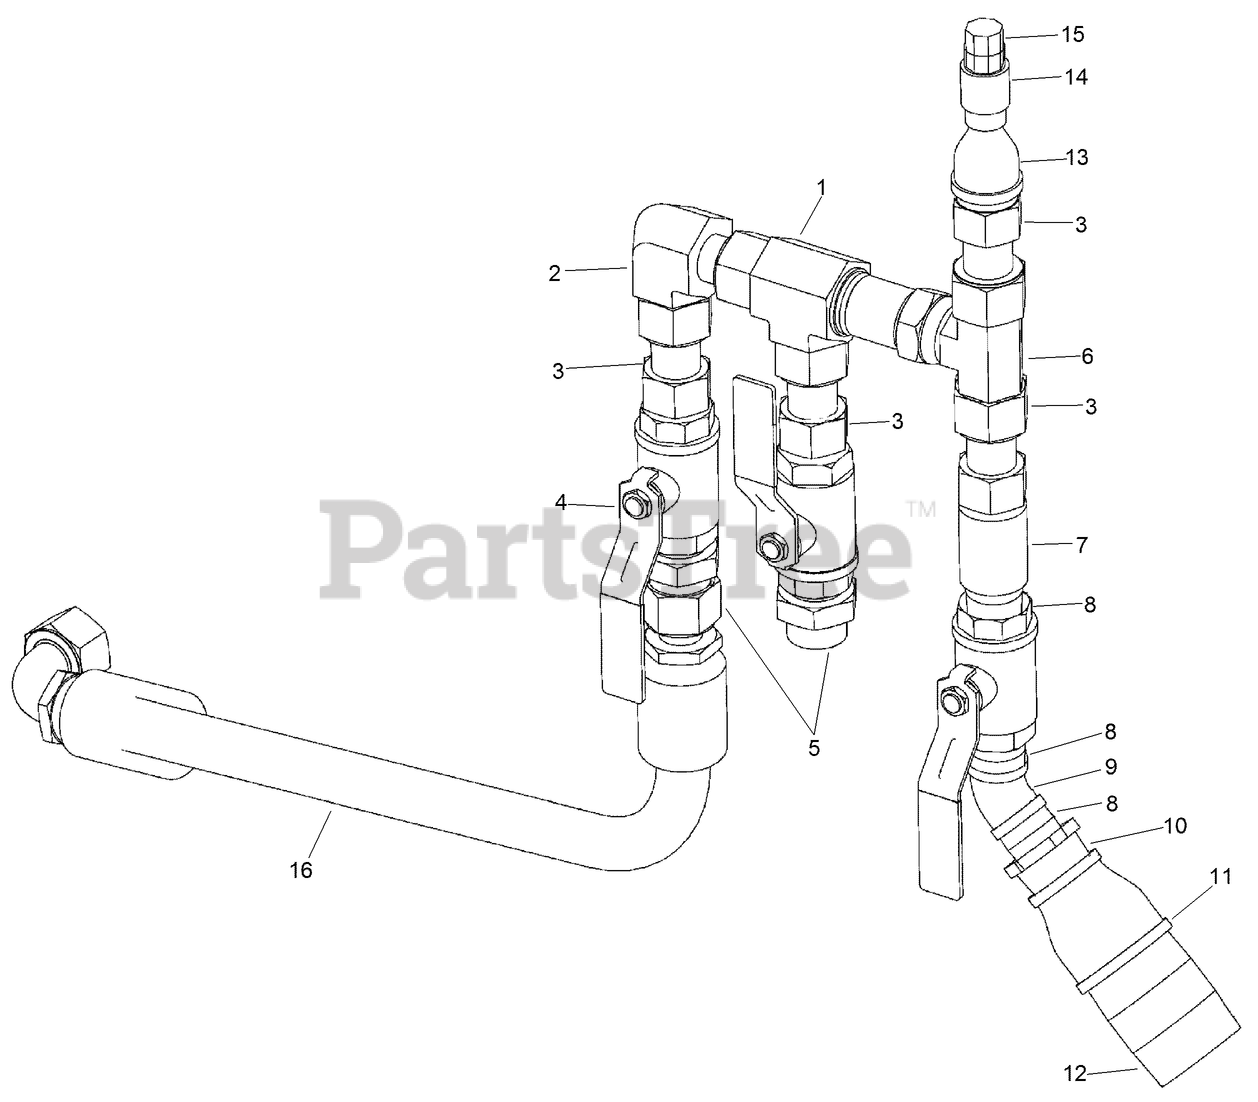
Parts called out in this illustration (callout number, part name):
1	FITTING-TEE, BULKHEAD
2	CONNECTION - 90 Degree, -16 ORFS / -16 ORFS
3	FITTING-STRAIGHT
4	VALVE-BALL
5	FITTING-STRAIGHT
6	FITTING-TEE
7	COUPLING-PIPE
8	NIPPLE-PIPE
9	FITTING-ELBOW, 45 DEG
10	FITTING-REDUCER
11	FITTING-REDUCER, BELL
12	NIPPLE-PIPE
13	FITTING-REDUCER
14	NIPPLE-CONNECT, QUICK
15	CAP-DUST, PLASTIC
16	HYD HOSE ASM
